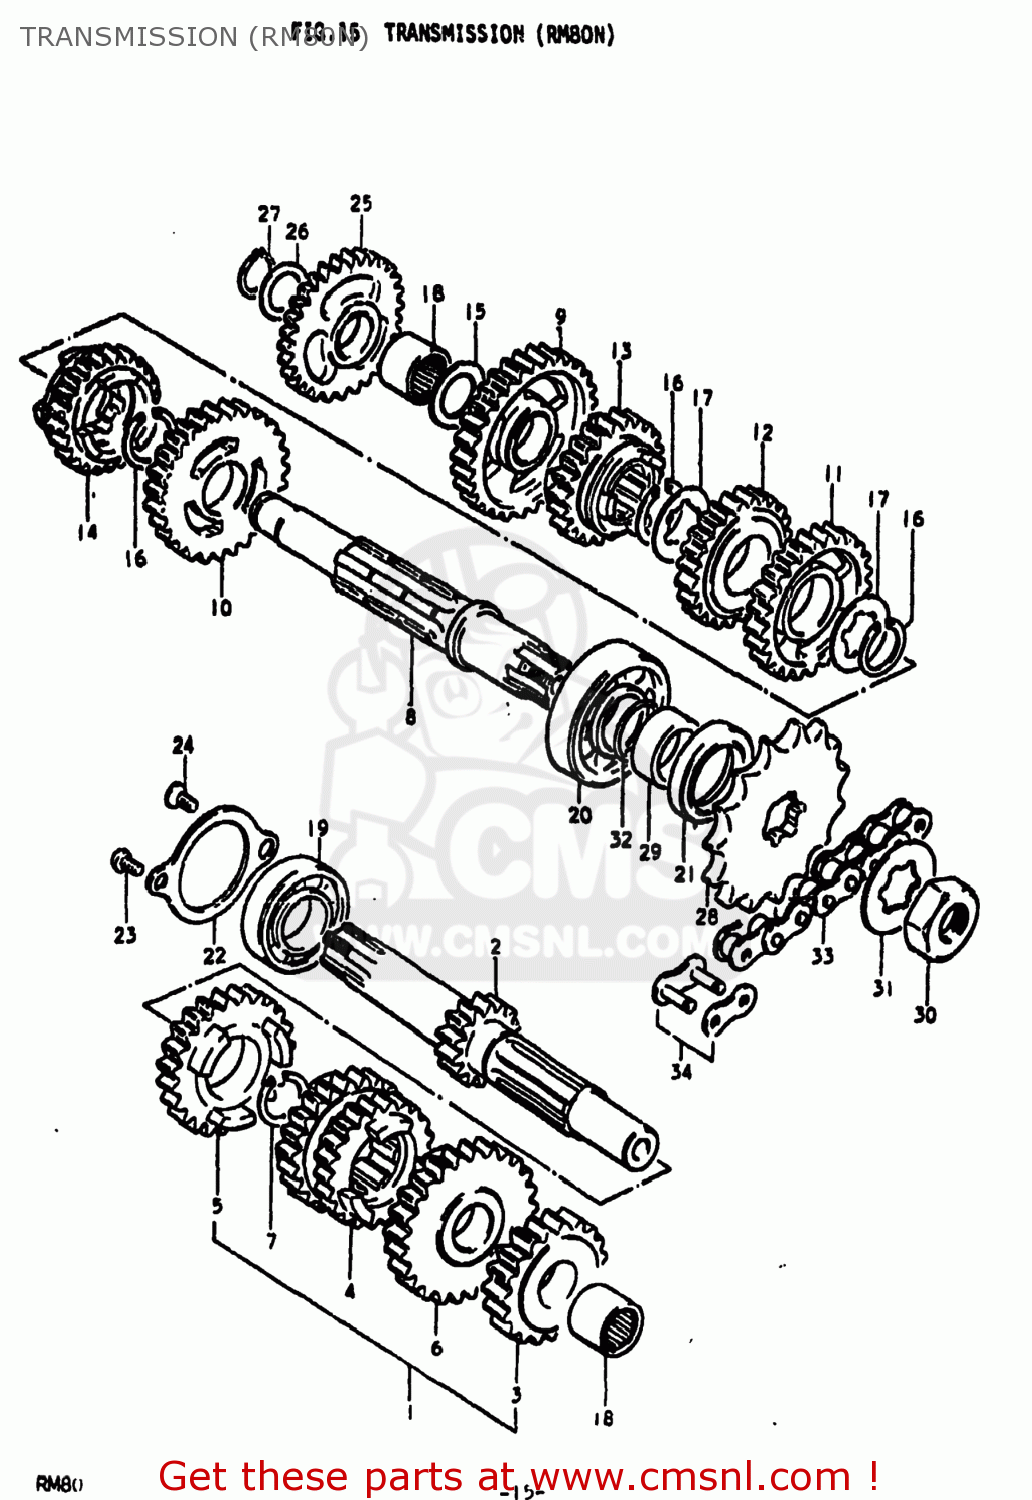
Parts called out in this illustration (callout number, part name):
1	SHAFT,COUNTER
2	SHAFT,COUNTER
3	GEAR,SECOND DRIVE
4	GEAR,THIRD/FOURTH DRIVE
5	GEAR,FIFTH DRIVE
6	GEAR,SIXTH DRIVE
7	CIRCLIP
8	SHAFT,DRIVE
9	GEAR,FIRST DRIVEN
10	GEAR,SECOND DRIVEN
11	GEAR,THIRD DRIVEN
12	GEAR,FOURTH DRIVEN
13	GEAR,4TH DRIVEN(NT:36)
14	GEAR,SIXTH DRIVEN
15	WASHER(13X24X1)
16	CIRCLIP
17	WASHER,LOCK
18	ROLLER BEARING (13X19X1
19	BEARING
20	BEARING
21	SEAL,OIL(21X35X5)
22	RETAINER,CNTR SHAFT BEARING
23	SCREW
24	SCREW
25	GEAR,KICK STARTER IDLE
26	WASHER
27	CIRCLIP
28	SPROCKET,ENGINE
29	SPACER (17X21X11)
30	NUT
31	WASHER,LOCK
32	O RING(D:1,ID:16.8)
33	CHAIN ASSEMBLY,DRIVE
34	JOINT ASSEMBLY,CHAIN
